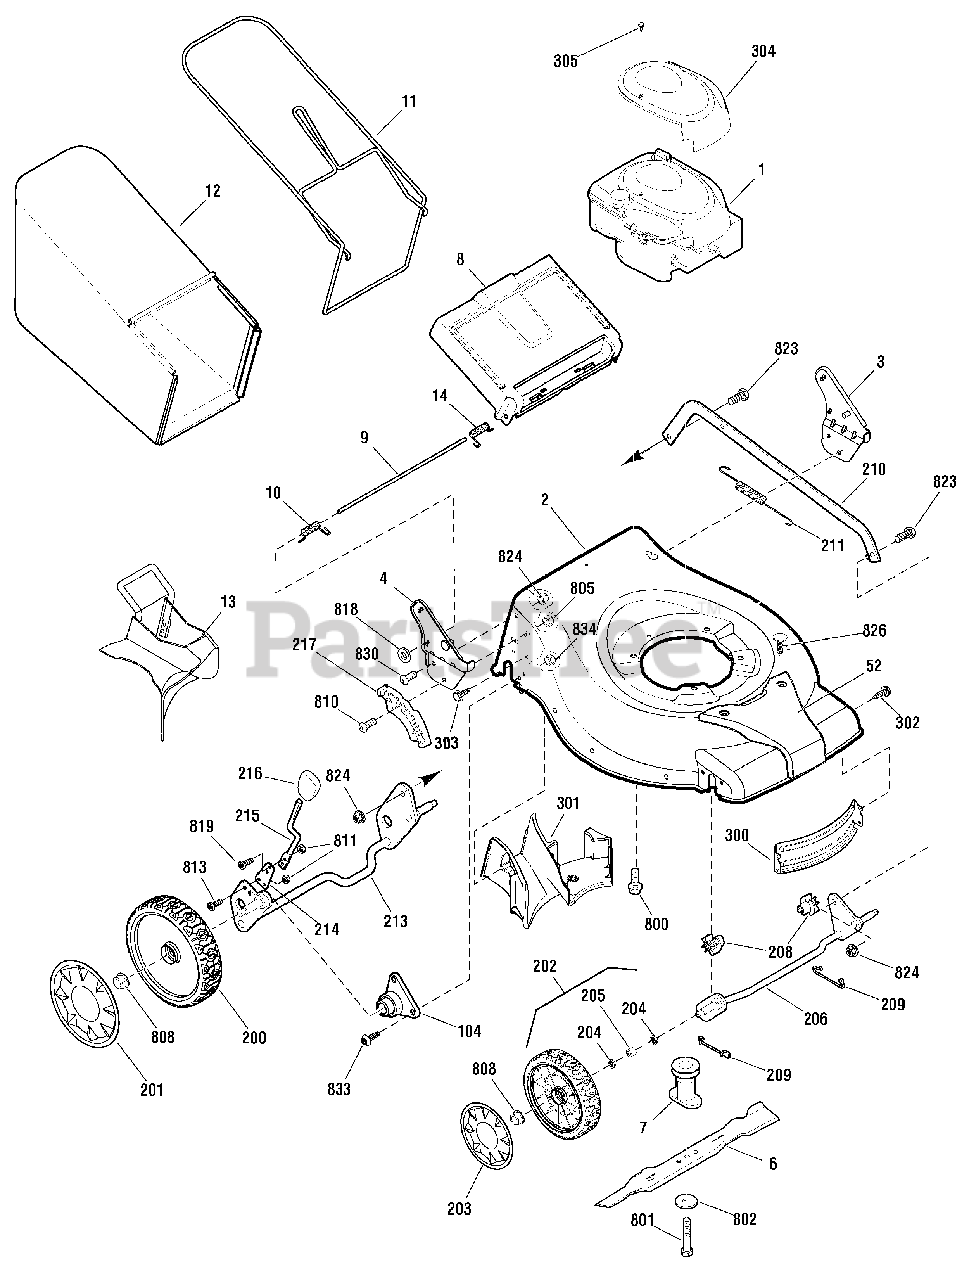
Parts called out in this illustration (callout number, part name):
1	* ENGINE, B&S 550 Series EU
2	MOWER HOUSING
3	BRACKET ASSEMBLY, Left Handle
4	BRACKET ASSEMBLY, Right Handle
6	BLADE, 16"
7	BLADE ADAPTER ASSEMBLY
8	DOOR, Rear
9	ROD, Rear Door
10	SPRING, Torsion Rear Door, Right
11	FRAME ASSEMBLY
12	BAG ASSEMBLY
13	MULCH PLUG
14	SPRING, Torsion Rear Door, Left
52	HOUSING COVER, Front
104	SLEEVE ASSEMBLY, Rear Axle
200	WHEEL, Rear
201	HUBCAP, Rear
202	WHEEL, Front, Complete
203	HUBCAP, Front
204	WHEEL BEARING (Not Available)
205	SPACER (Not Available)
206	CROSSBAR ASSEMBLY, Front
208	BUSHING, Front Crossbar
209	SPRING, Clip Crossbar
210	LINK, Single Lever
211	SPRING, Extension
213	REAR CROSSBAR
214	SPRING, Adjuster
215	LEVER, Height Adjustment
216	KNOB, Adjuster
217	BRACKET, Height Adjuster
300	BAFFLE, Front
301	BAFFLE, Rear
302	SCREW, Pan Head, Taptite, 1/4-20 x 1/2
303	SCREW, Pan Head, HI-LO, 1/4-15 x 5/8
304	SHROUD, With Label
305	SCREW, Hex Washer Head
800	SCREW, Hex Head, 3/8-16 x 1
801	BOLT, Blade, 3/8-24 x 2
802	WASHER, Belleville
805	NUT, Nylock, M8 x 1-1/4
808	NUT, Flange, 3/8-16
810	BOLT, Hex Key Head
811	NUT, Nylock
813	SCREW, Torx Head, M5 x .8 x 14mm
818	PUSHNUT, 1/4
819	SCREW, Torx Head, M5 x .8 x 12.5mm
823	BOLT, Shoulder, 5/16-18 x 1
824	Nut, Flange, 5/16-18
826	SCREW, Truss Head Torx, 1/4-20 x 7/8
830	SCREW , 5/16-18 x 3/4
833	SCREW, Torx, 1/4-20 x 5/8
834	NUT, Flange Lock, 1/4-20
